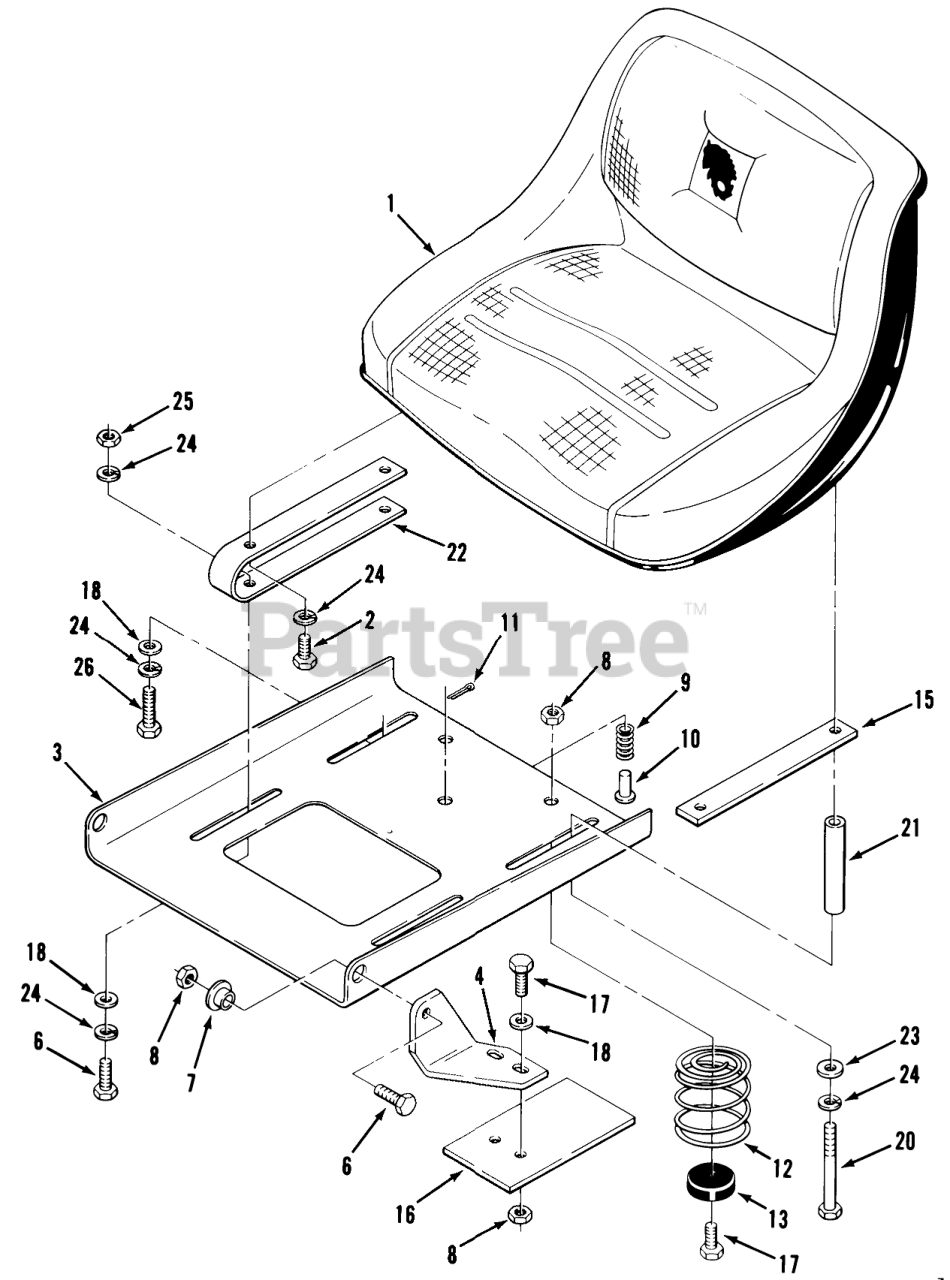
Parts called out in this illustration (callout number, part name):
4	BRACKET-PIVOT R.H *B (NS)
4	BRACKET-PIVOT L.H *B
7	BUSHING
9	SPRING-SEAT SWITCH
12	SPRING-SEAT NYLON
13	BUMPER
18	WASHER 5/16 SAE
21	SPACER SEAT *B
